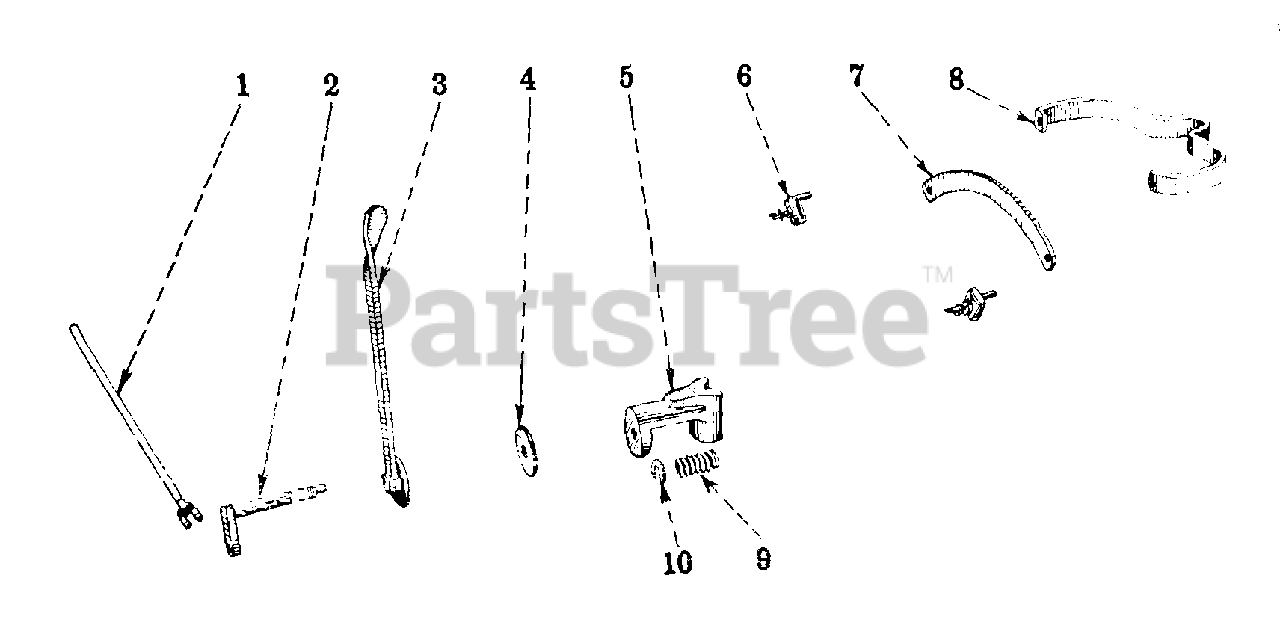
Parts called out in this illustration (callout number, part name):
1	ROD ASSY, CONTROL
2	SHAFT AND ARM ASSY, HAND CONTROL LEVER
3	LEVER ASSY, HAND CONTROL
4	DISC, HAND CONTROL FRICTION
5	BRACKET, HAND CONTROL
6	INDICATOR ASSY, HYD LIFT STOP
7	QUADRANT, HAND CONTROL
8	SUPPORT, HAND CONTROL QUADRANT
9	SPRING, HAND CONTROL FRICTION
10	RETAINER, HAND CONTROL FRICTION SPRING
